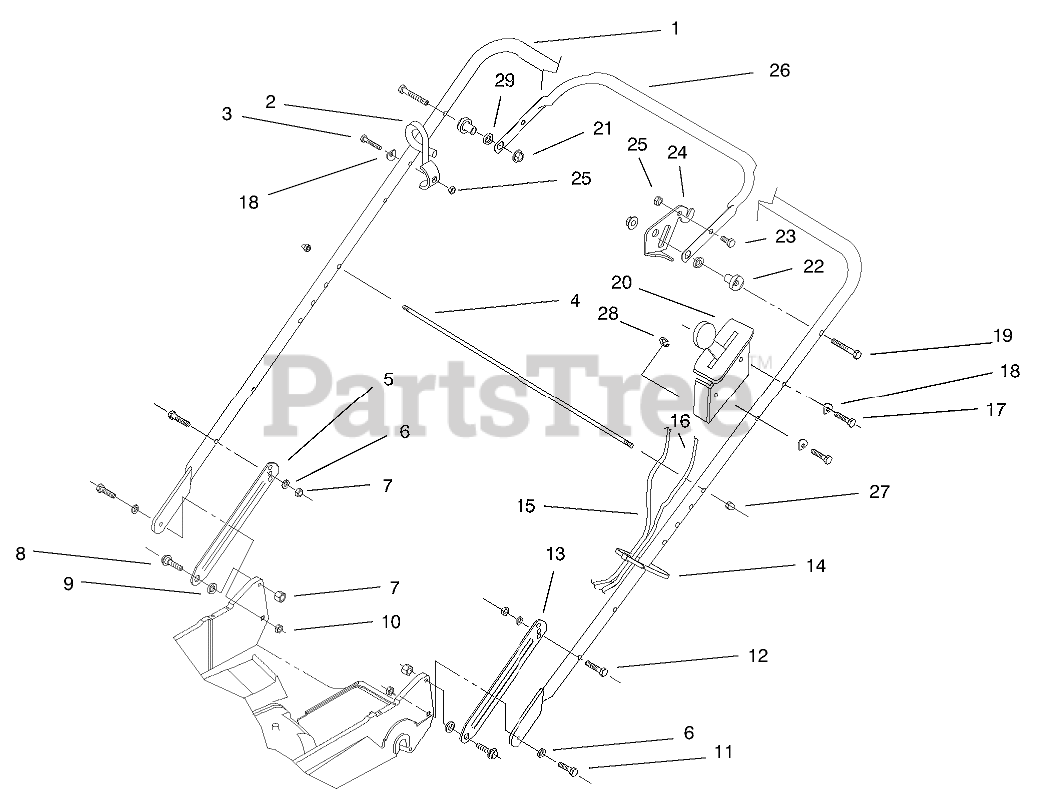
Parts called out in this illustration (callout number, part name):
2	GUIDE-ROPE
3	SCREW-HH
4	ROD-SUPPORT, BAG
5	LATCH-HANDLE, RH
6	WASHER-BELLEVILLE
7	NUT-LOCK, NI
8	SCREW-SHOULDER
9	SPACER
10	NUT-LOCK, NI
11	SCREW-HH
12	SCREW-HH
13	LATCH-HANDLE, LH
14	TIE-CABLE
15	CABLE-BRAKE
16	CABLE-THROTTLE
17	SCREW-HH
18	WASHER
19	SCREW-HH
20	BRACKET-CONTROL, THROTTLE
21	NUT-LOCK, NI
22	SPACER-SUPPORT
23	SCREW-HH
24	LEVER-CONTROL
25	NUT-LOCK, NI
26	BAR-CONTROL
27	NUT-CAP
28	E-RING
29	SPACER-NYLON
